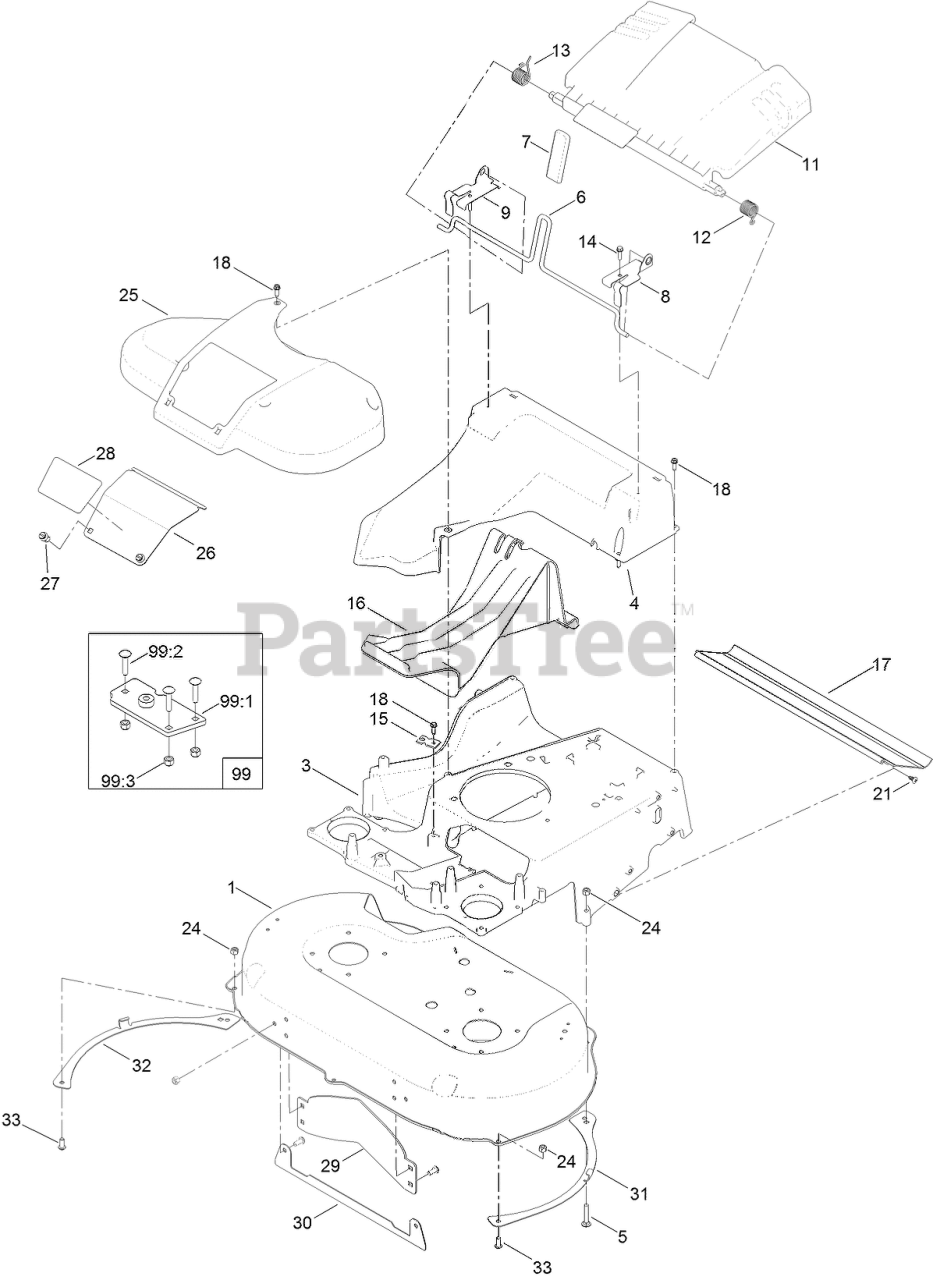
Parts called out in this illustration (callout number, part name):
1	HOUSING ASM
4	CHUTE
5	SCREW-CARR
6	ROD-RELEASE, HANDLE
7	GRIP-LEVER
8	BRACKET-DOOR, LH
9	BRACKET-DOOR, RH
11	REAR DEFLECTOR ASM
12	SPRING-TORSION
13	SPRING-TORSION
14	SCREW-HWH
15	BRACKET-CABLE, TRACTION
16	PLUG-MULCH
17	SHIELD-TRAILING
18	SCREW-HWHTF
21	SCREW-PTH
24	NUT-LOCK, NI
25	COVER-BELT
26	DOOR-ACCESS
27	FASTENER
28	DECAL-ACCESS PANEL
29	BAFFLE-CONTROL
30	PLATE-DECK
33	SCREW-HSBH
99	FRAME PLATE KIT
99:1	PLATE-FRAME
99:2	SCREW-CARR
99:3	NUT-LOCK, NI
